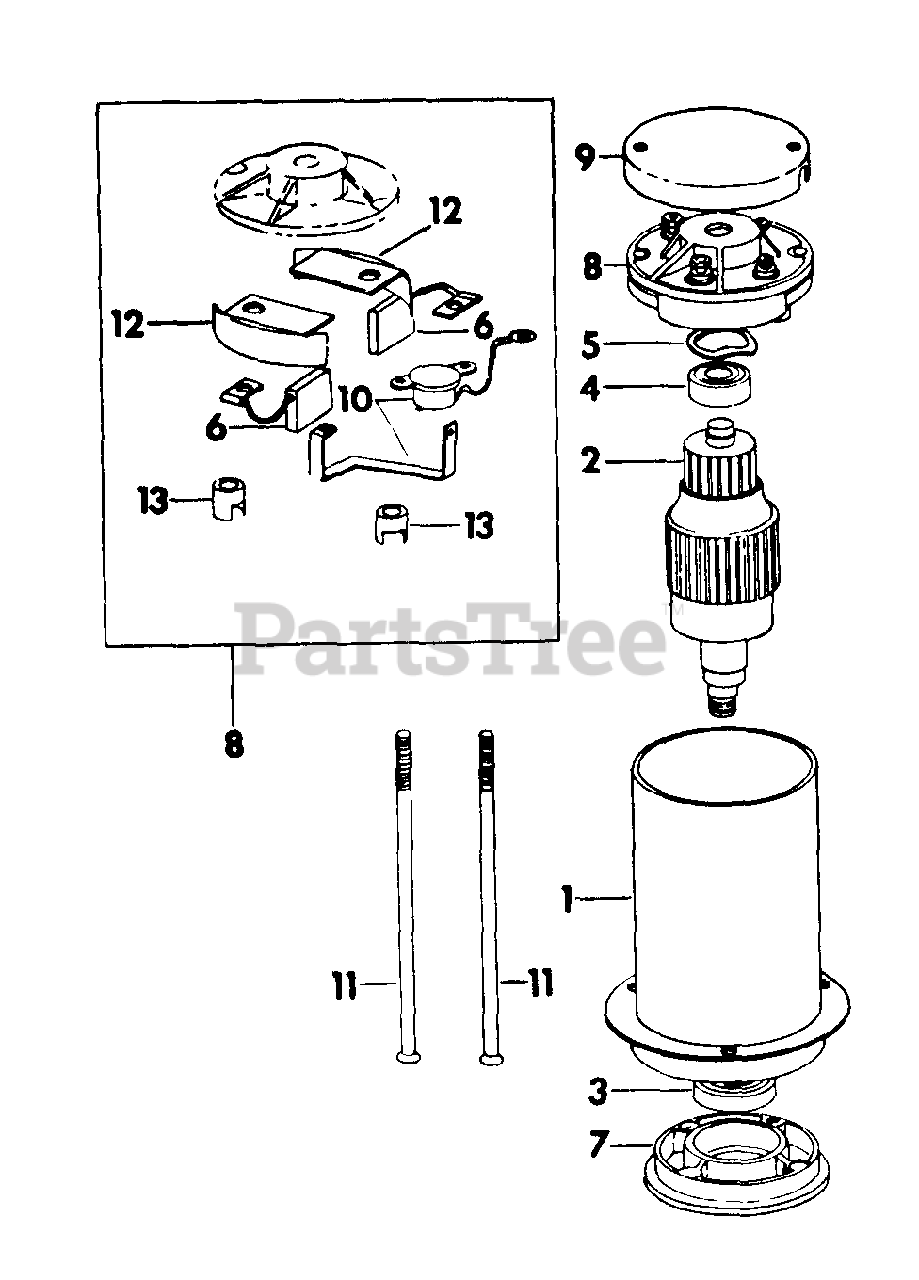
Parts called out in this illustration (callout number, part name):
1	SHELL ASSY W/MAGNETS
2	ARMATURE ASSY W/BRGS
3	BEARING, DRIVE END
4	BEARING, COMMUTATOR END
5	WASHER, WAVE THRUST
7	END, FRT BELL
8	END ASSY, REAR BELL
9	COVER, COMMUTATOR END
10	THERMOSTAT, BRUSH PLATE
12	MOTOR TERMINALS AND INSULATORS PACKAGE
13	SWITCH TERMINALS AND INSULATORS PACKAGE
